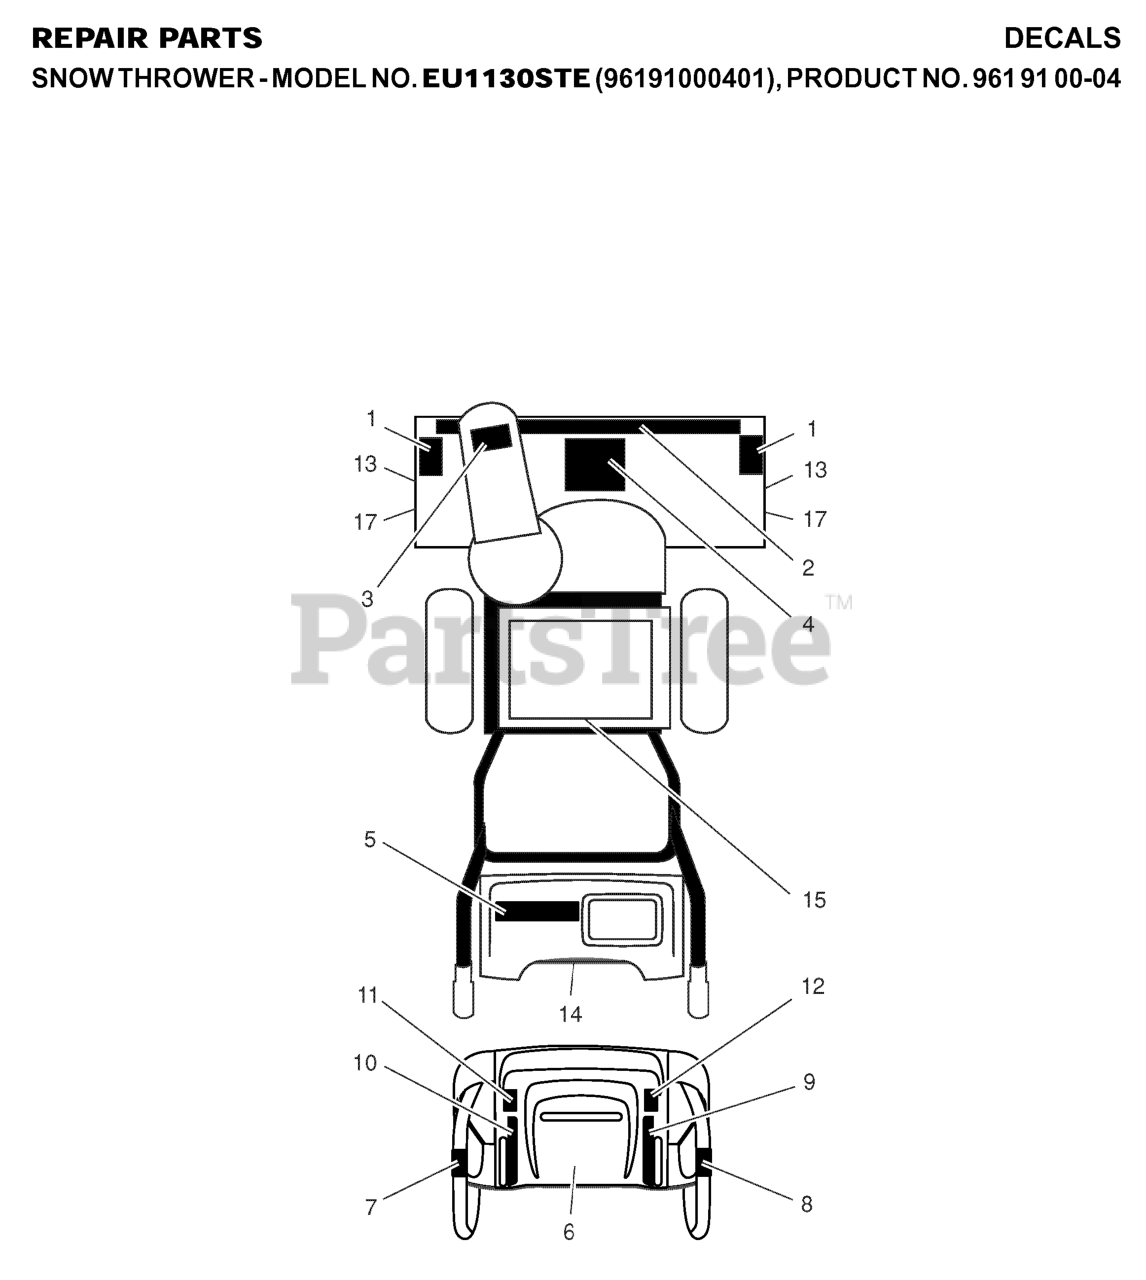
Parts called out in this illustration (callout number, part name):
1	DECAL.AUGER.SAFETY.
3	DECAL.CHUTE.SAFETY.
4	DECAL.AUGER."
6	DECAL.CONSOLE.INSTRUCTION
10	DECAL.REM.DEFLECTOR.LT
11	DECAL, LH TRIGGER
12	DECAL, RH TRIGGER
14	DECAL.FENDER
15	DECAL.BELT.GUARD.
17	DECAL, HUSQVARNA
